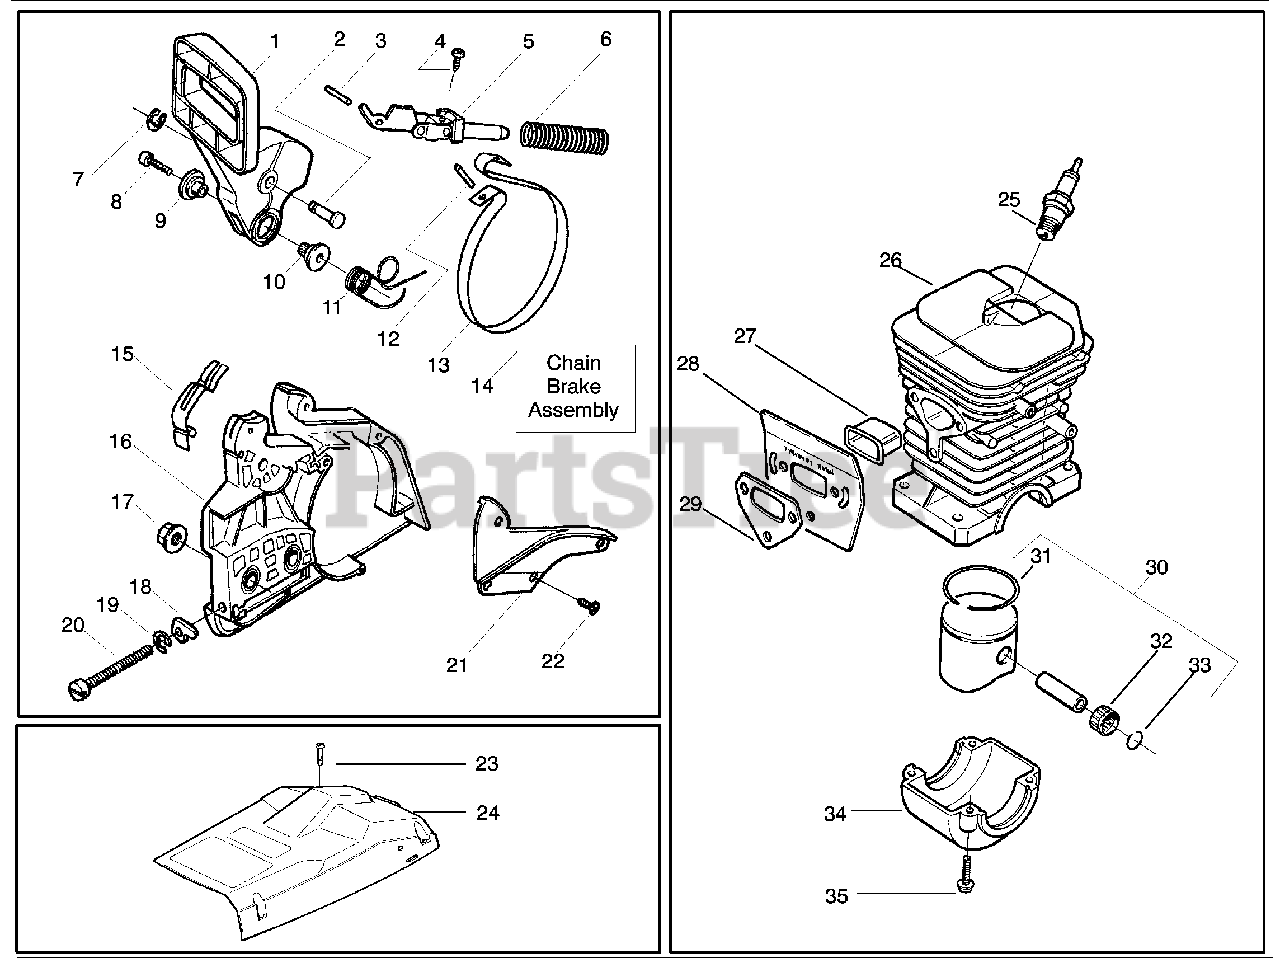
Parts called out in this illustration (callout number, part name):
1	Actuating Lever
4	Screw
5	Front Link Ass'y.
6	Chain Brake Spring
9	Journal-Right
10	Journal-Left
11	Handguard Spring
12	Pin-Spring
13	Brake Band
14	Chain Brake Assembly
15	Position Spring
16	Clutch Cover
18	Bar Adjusting Pin
20	Screw-Bar Adjusting
21	Chain Brake Spring Cover
22	Screw
24	Cylinder Shield Ass'y.
25	Spark Plug (RCJ-7Y)
26	Kit-Cylinder
27	Heat Insulator
28	Muffler-Plate
29	Muffler Gasket
30	Piston Kit
31	Piston Ring
31	(141)
32	Piston Pin Bearing
33	Piston Pin Retainer
34	Cap-Crankcase
